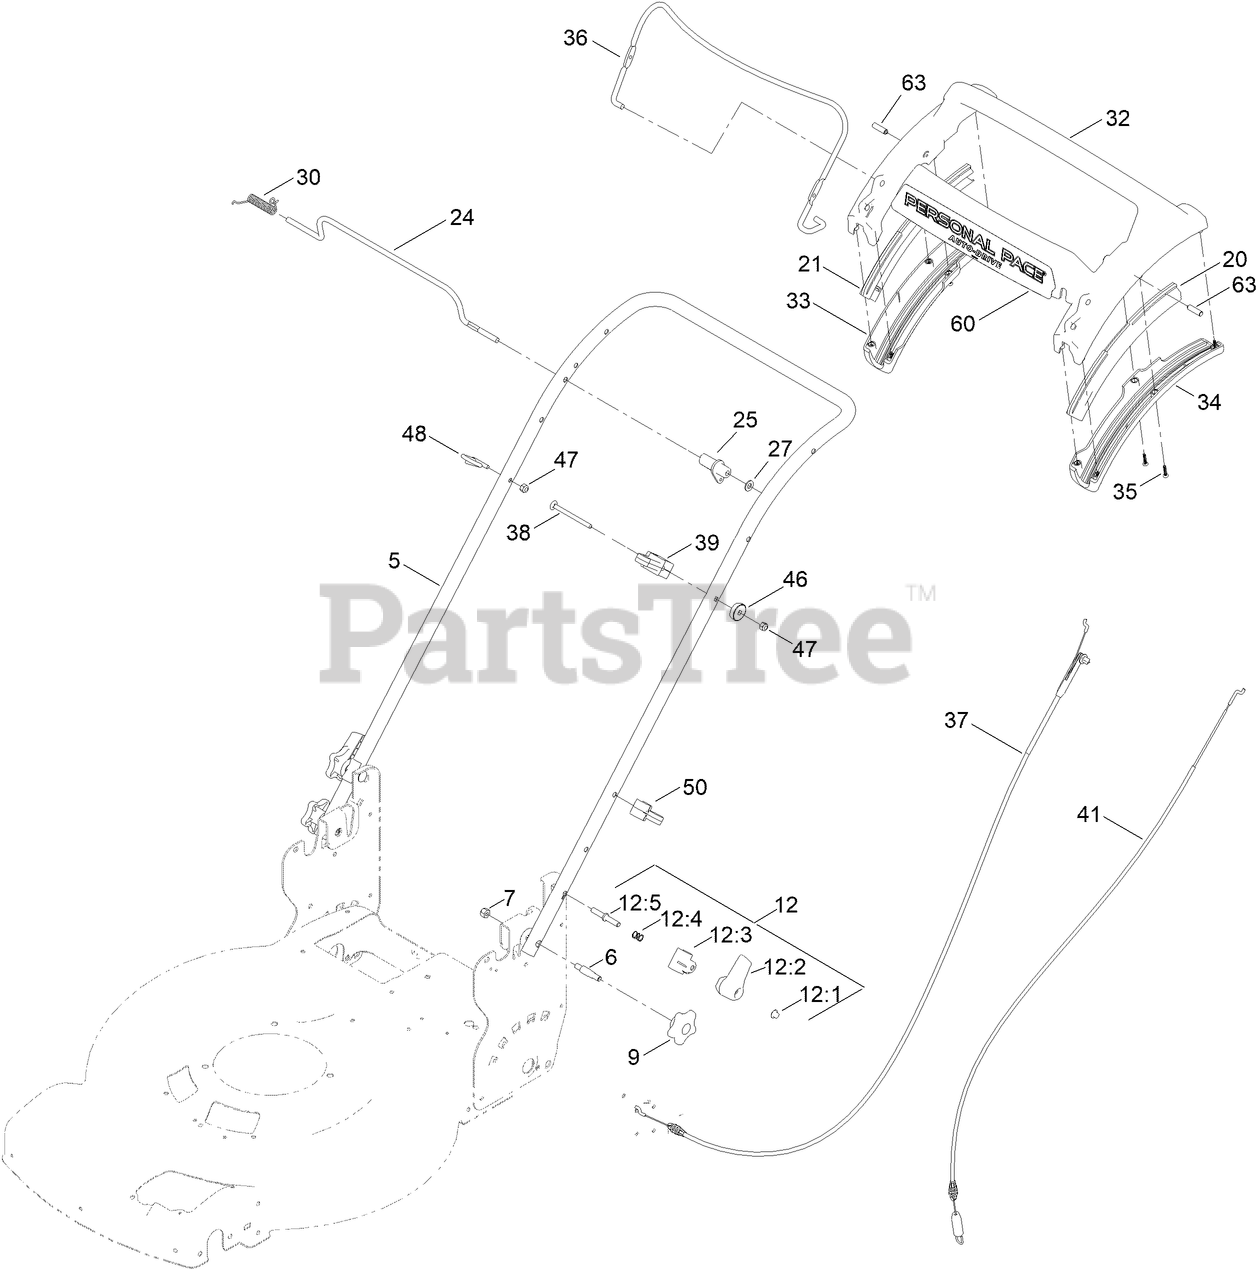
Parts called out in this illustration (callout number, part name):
5	HANDLE-CURVED
6	BOLT-SHOULDER, HANDLE
7	NUT-LOCK, NI
9	KNOB-HANDLE
12	QUICK RELEASE ASM
12:1	NUT-PUSH
12:2	LEVER-RELEASE
12:3	ANCHOR-SPRING
12:4	SPRING-COMPRESSION
12:5	ROD-RELEASE
20	GUIDE-CURVED, LH (RWD)
21	GUIDE-CURVED, RH (RWD)
24	ROD-CONTROL, TRACTION
25	LEVER-TRACTION, RWD
27	WASHER-PLAIN
30	SPRING-TORSION
32	HANDLE-PERSONAL PACE, CURVED
33	BOTTOM-HANDLE, RH
34	BOTTOM-HANDLE, LH
35	SCREW-PPH
36	BAIL-BRAKE
37	CABLE-BRAKE, PP BS
38	SCREW-CARR
39	ANCHOR-CABLE, RWD
41	CABLE-TRACTION, RWD (PP)
46	WASHER-CURVED
47	NUT-LOCK, NI
48	GUIDE-ROPE
50	GUIDE-CABLE
63	PIN-HANDLE, PP
